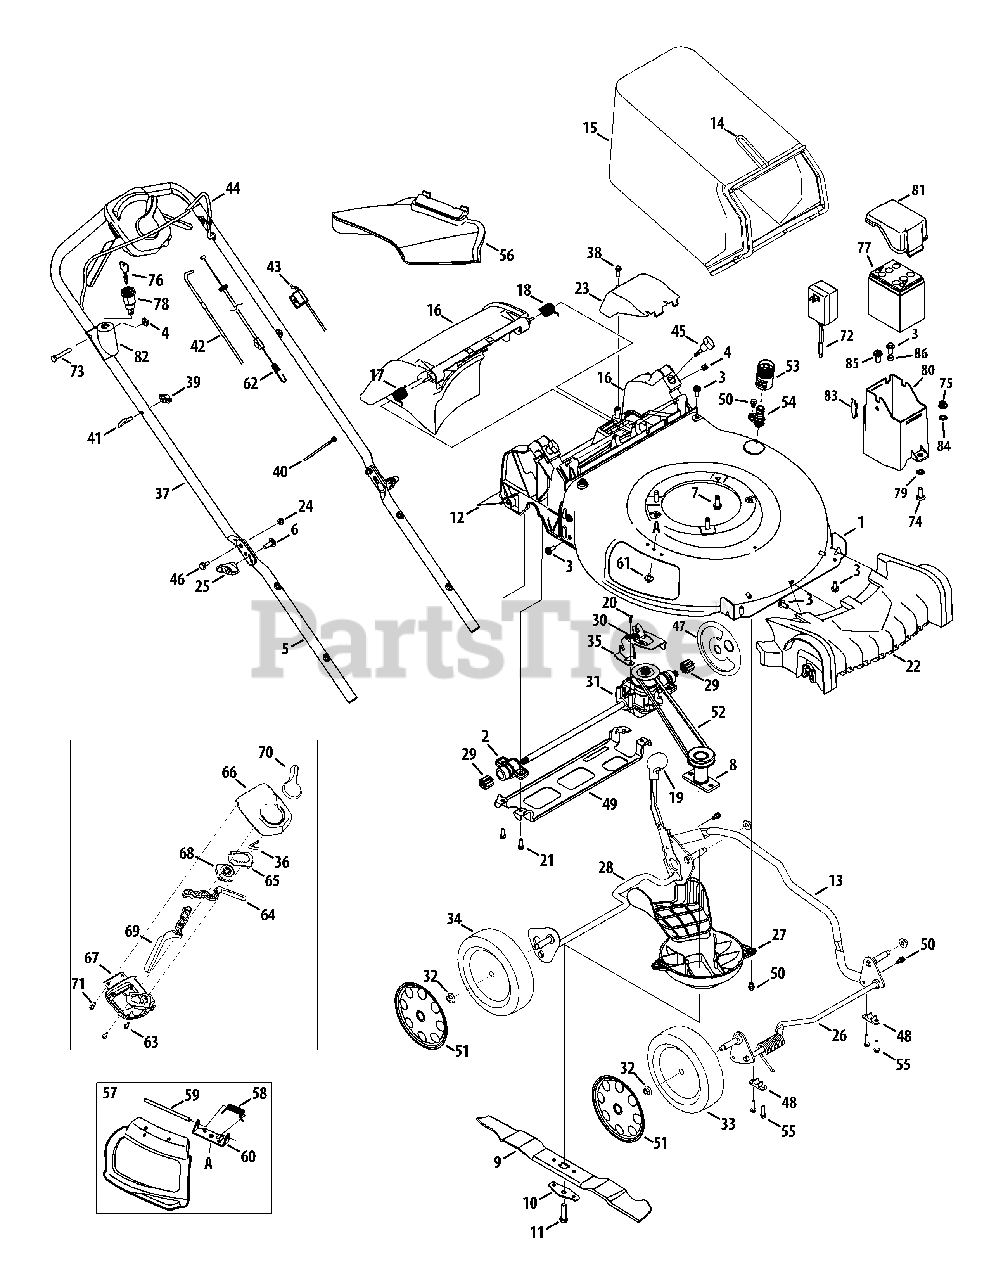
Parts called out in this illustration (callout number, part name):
1	Deck , 21"
2	Bearing Assembly
3	Screw, 5/16-14 x .750
4	Nut, Sq., 1/4-20
5	Lower Handle
6	Carriage Screw ,5/16-18
7	Screw, 3/8-16 x 1.00
8	Blade Adapter
9	Mulching Blade
10	Blade Bell Support
11	Screw, 3/8-24 x 1.50
12	Trailing Shield
13	Cross Bracket
14	Grass Catcher Frame
16	Rear Discharge Door Assembly
17	Torsion Spring - RH
18	Torsion Spring - LH
19	Adjustment Lever Knob
20	Screw, Hex Washer, .159 x .43
21	Screw, 1/4-15 x 1.25
22	Front Cover No logo
22	Front Cover w/Troy Bilt logo
23	Transmission Cover
24	Nut, Flange Lock, 1/4-20
26	Front Axle Assembly
27	Engine Baffle
28	Rear Axle Assembly
29	Spur Gear, 10T
30	Exten. Spring, 2.405
31	Transmission Assembly
32	Flange Lock Nut, 3/8-16
33	Front Wheel
34	Rear Wheel
35	Transmission Bracket
38	Screw, 1/4-15 x .750
40	Cable Tie
41	Rope Guide
42	Speed Adjustment Cable
43	Control Cable
45	Wing Nut
46	Sldr. Screw, .375 x .126 x 1/4-20
47	Wheel Dust Cover
48	Bushing, Lock, .505 Dia. X .62
49	Rear Support Bracket
50	Screw., Shldr., 1/4-20 x .50
51	Hubcap, 8"
53	Water Nozzle Adapter
54	Water Nozzle
55	Screw, 1/4-15 x 1.000
56	Side Discharge Chute
57	Mulch Plug (Incl. 58-60)
58	Torsion Spring
60	Chute Deflector Bracket
61	Screw, 1/4-20 x .500
62	Drive Cable
63	Screw, 1/4-15 x .750
64	Control Lever LH
65	Cable Adjust Plate
66	Upper Housing
67	Lower Housing
68	Speed Adjust Actuator
69	Control Lever RH
70	Speed Select Lever
71	Screw, Shldr, 1/4-15 x .970
72	Battery Charger
73	Screw, 1/4-20 x 1.75
74	Bolt, Carr., 5/16-18 x 1.00
75	Nut, Flglk., 5/16-18
77	Battery
78	Key Switch
79	Speed Nut
80	Battery Housing
81	Battery Housing Top
82	Electric Start Housing
83	Lid Seal
84	Washer, Bell, .340 x .872 x .080
85	Screw, Sldr., 5/16-14 x .972
86	Spacer, .340 x .460 x .246
